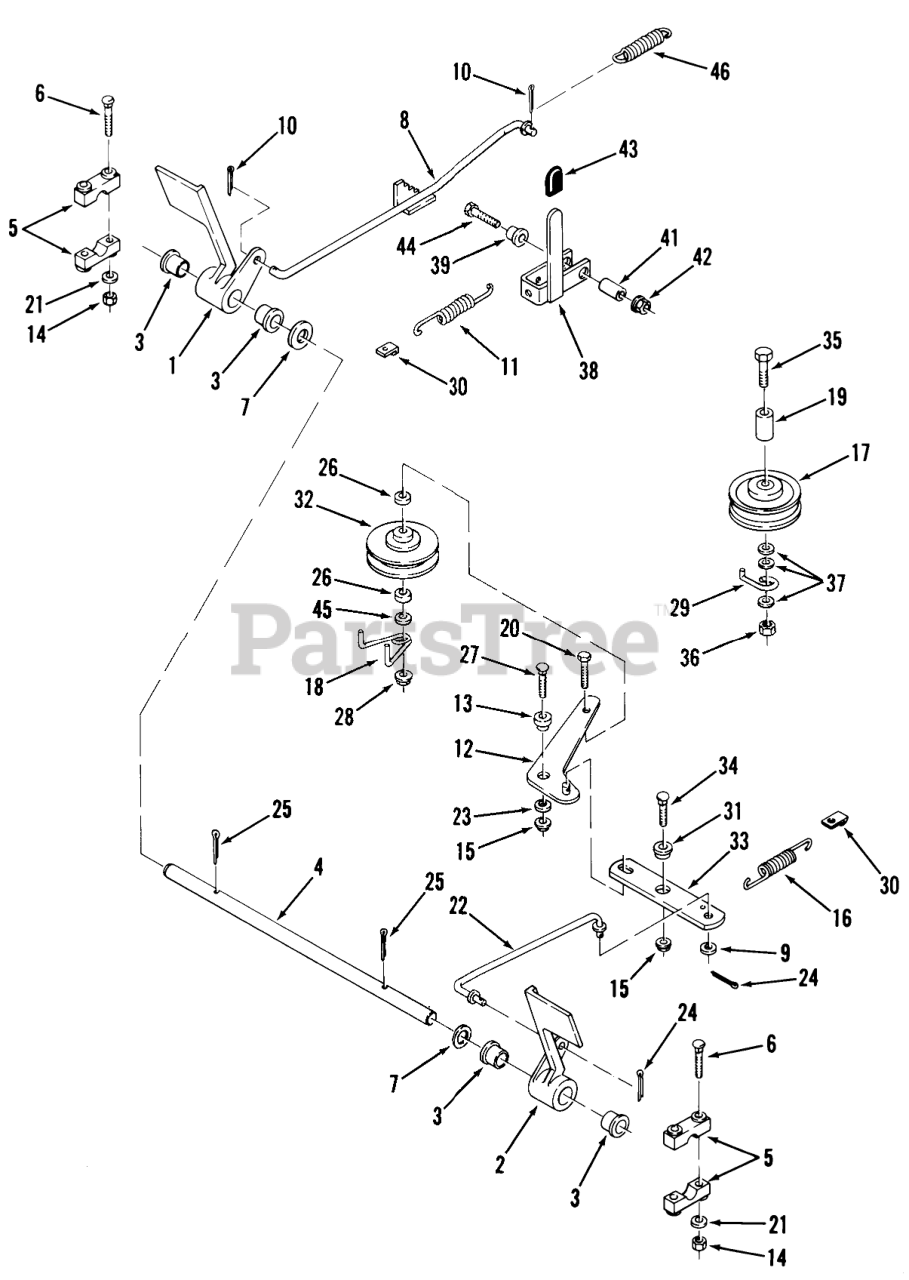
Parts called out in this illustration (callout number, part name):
1	Pedal-Brake (Includes Item 3)
2	Pedal-Clutch (Includes Item 3)
3	BEARING
4	Shaft-Pedal
5	BLOCK PIVOT
6	Washer
7	Washer
8	Assy-Brake Rod
9	WASHER 5/16 SAE
10	Pop Rivet
11	SPRING-EXTENSION
12	IDLER ARM ASSY R
13	SPACER-IDLER ARM
14	Nut
15	LOCKNUT-FLANGE
16	SPRING
17	PULLEY-IDLER STATION
18	BELT GUIDE
19	SPACER
20	Bolt
21	WASHER 5/16 SAE
22	ROD-CLUTCH R
23	Washer
24	Pop Rivet
26	SPACER
27	Carriage Bolt
28	LOCKNUT-FLANGE
29	RETAINER-BELT
30	CLIP - SPRING
31	SPACER
32	IDLER PULLEY
32	Pully-Idler
33	BAR-CLUTCH
34	Bolt
35	Bolt 3/8-16 x 3 1/4
36	Nut
37	Washer
38	PAWL-HANDLE ASSY
39	SPACER
41	SPACER
42	LOCKNUT-FLANGE
43	GRIP
44	Bolt
45	Washer
46	SPRING-EXTENSION
